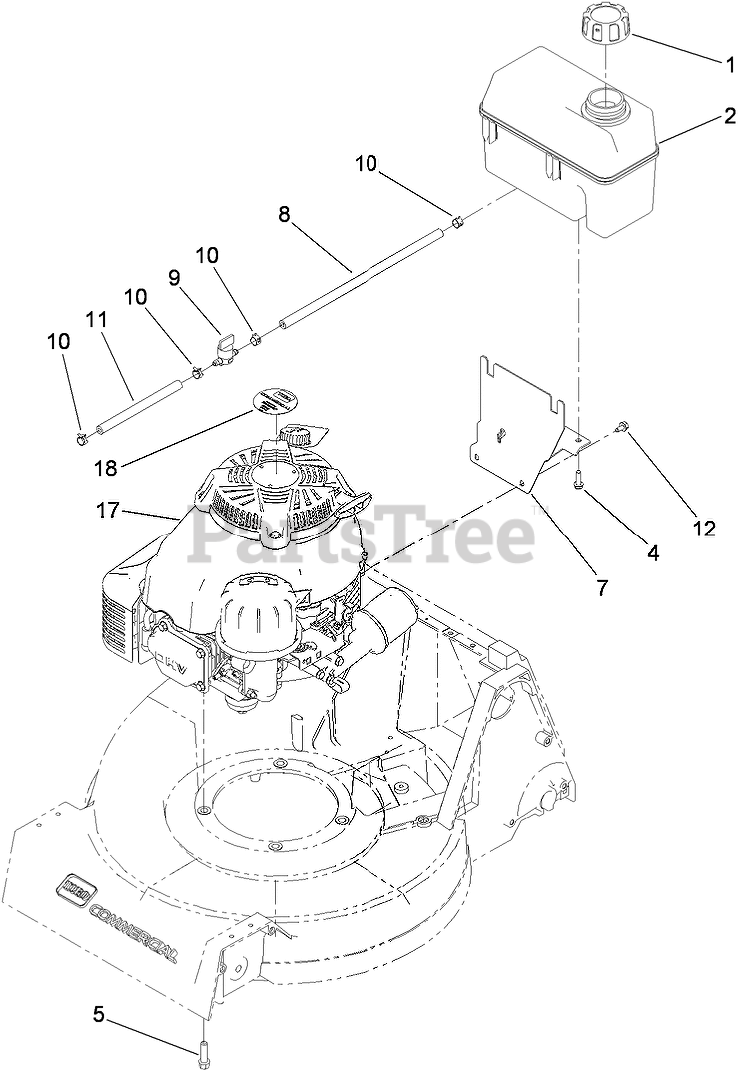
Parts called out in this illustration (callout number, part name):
1	CAP-GAS
2	TANK-FUEL
4	SCREW-HWH
5	SCREW-TAPTITE
7	MOUNT-TANK
8	HOSE-FUEL
9	VALVE-FUEL
10	CLAMP-HOSE
11	HOSE-FUEL
12	SCREW-HWH
17	ENGINE-KAWASAKI, FJ180V-AM07-M
